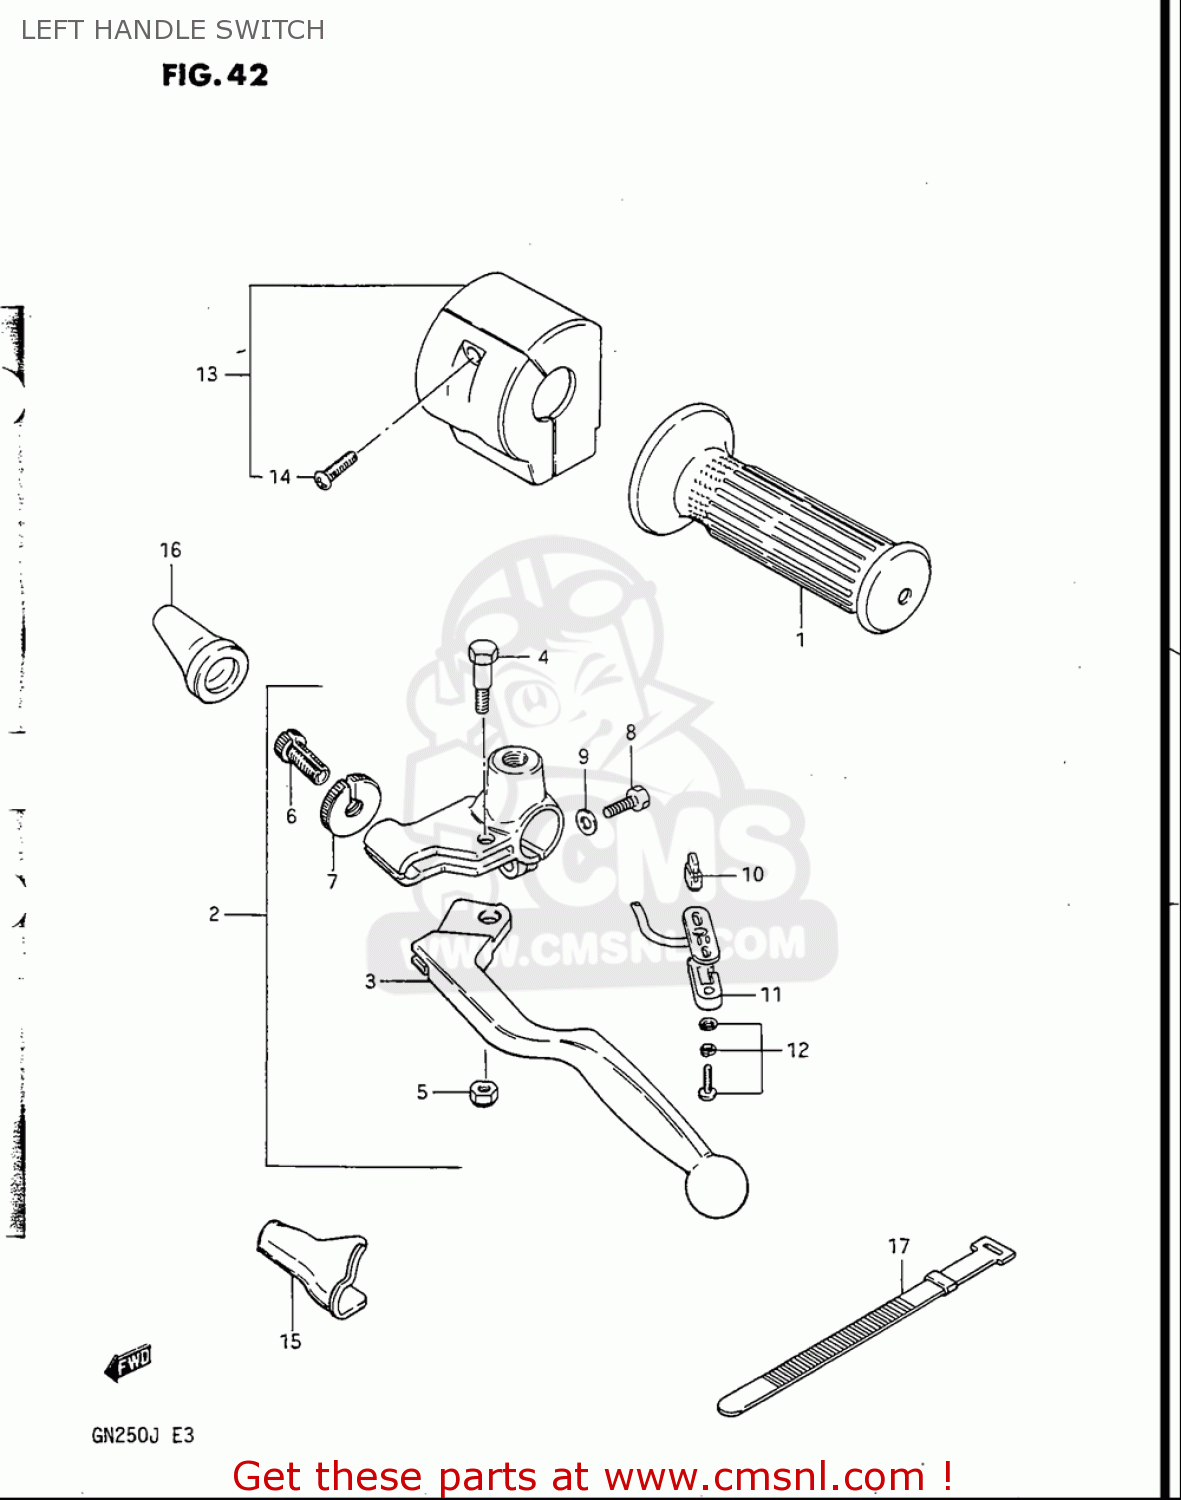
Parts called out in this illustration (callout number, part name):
1	GRIP,L
2	LEVER ASSY,CLUTCH
3	LEVER,CLUTCH
4	BOLT,LEVER PIVOT
5	NUT 6MM
6	ADJUSTER,CABLE
7	NUT,CABLE ADJUSTER
8	BOLT
9	WASHER
10	CONTACT,SWITCH
11	COVER,FR BK TERMINAL BASE
12	SCREW
13	SWITCH ASSEMBLY,HANDLE,LEFT
14	SCREW
15	COVER,CLUTCH LEVER
16	BOOT,CLUTCH CABLE
17	CLAMP(L:120)
